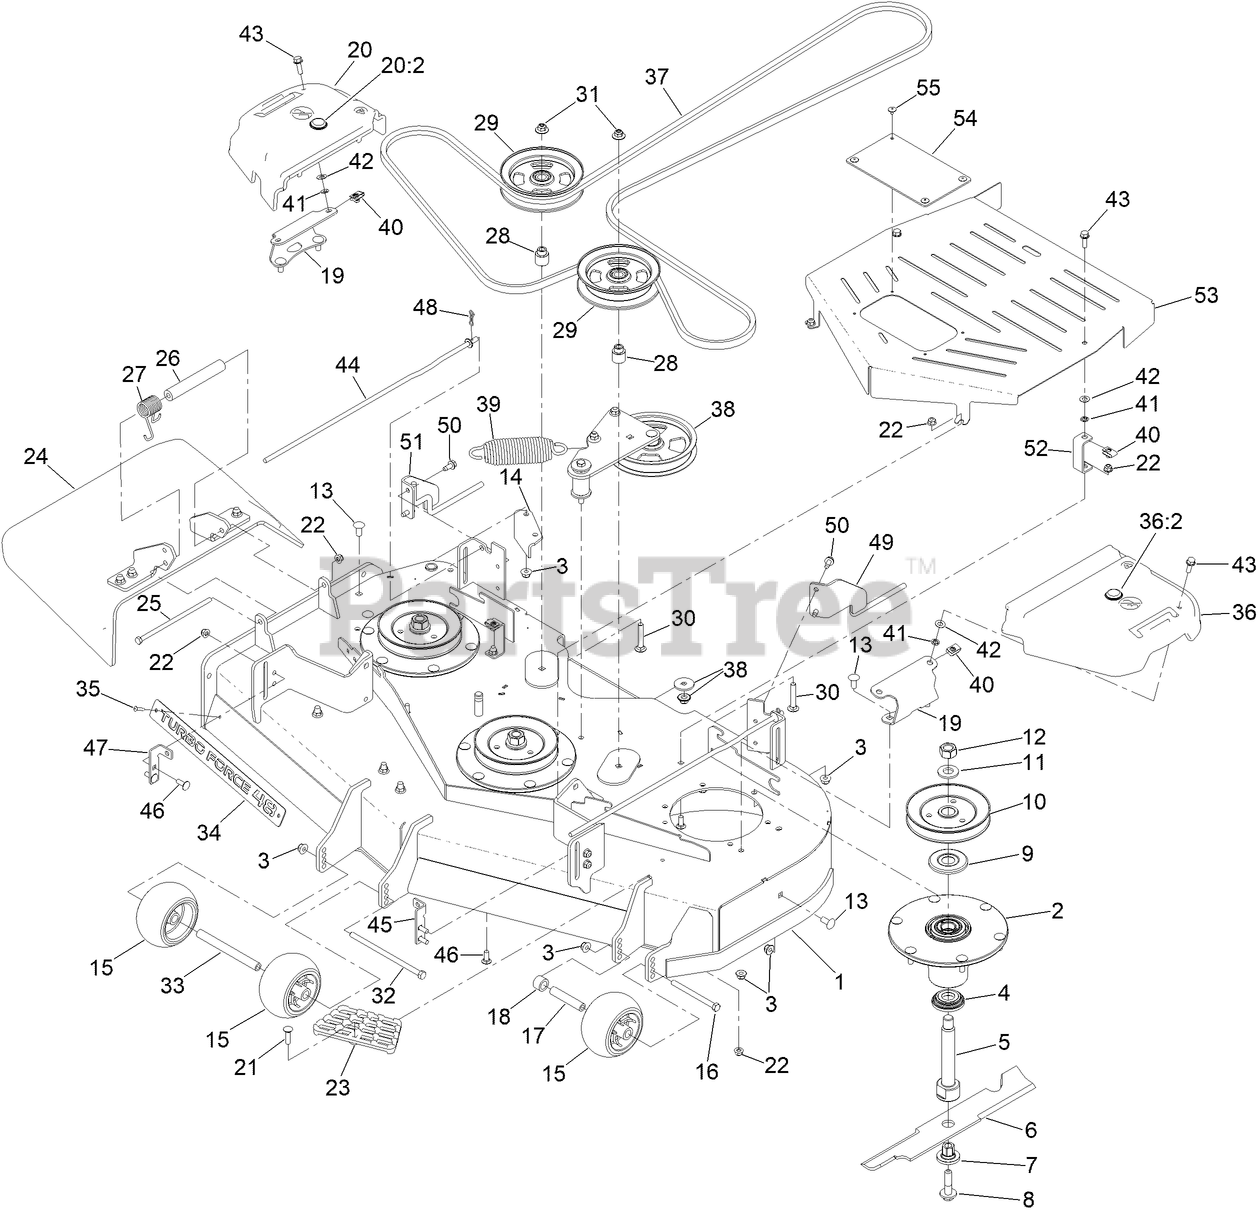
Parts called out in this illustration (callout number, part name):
1	DECK DECAL ASM
2	SPINDLE ASM
3	NUT-HF, NI
4	GUARD-BOTTOM
5	SHAFT-SPINDLE
6	BLADE-16.50 HIGH FLOW
7	BUSHING-HEX
8	SCREW-SEMS
9	GUARD-BEARING, TOP
10	SHEAVE,BLADE DRIVE 5.91
11	WASHER
12	NUT-HEX
13	SCREW-CARR
14	BAFFLE-DISCHARGE
15	ROLLER-SCALP, ANTI
16	SCREW-HH
17	TUBE-SHAFTING
18	TUBE-SPACER
19	BRACKET-COVER, BELT
20	RH BELT COVER ASM
20:2	PLUG-PLASTIC
21	SCREW-CARR
22	NUT-HF, NI
23	STEP-DECK
24	RUBBER DEFLECTOR ASM
25	SCREW-HH
26	SPACER
27	SPRING-TORSION
28	BUSHING, IDLER
29	PULLEY-IDLER, FLAT
30	SCREW-CARR
31	NUT-FLANGE, NI
32	SCREW-HH
33	SPACER-WHEEL
34	PLATE-TURBO FORCE [BLACK]
35	RIVET-TRIFOLD
36	LH BELT COVER ASM
36:2	PLUG-PLASTIC
37	BELT-V
38	IDLER ARM ASM
39	SPRING-EXTENSION
40	NUT-U
41	NUT-PUSH
42	WASHER-THRUST
43	SCREW-HHF
44	ROD-SKIRT, LOWER
45	BRACKET-SUPPORT, LH
46	BOLT-CARR
47	BRACKET-SUPPORT, RH
48	PIN-COTTER, LOCKING
49	SUPPORT-LOWER LH
50	SCREW-HWHTF
51	SUPPORT-LOWER RH
52	BRACKET-GUARD
53	GUARD-CENTER BELT 48
54	SHIELD-RUBBER
55	RIVET-POP
